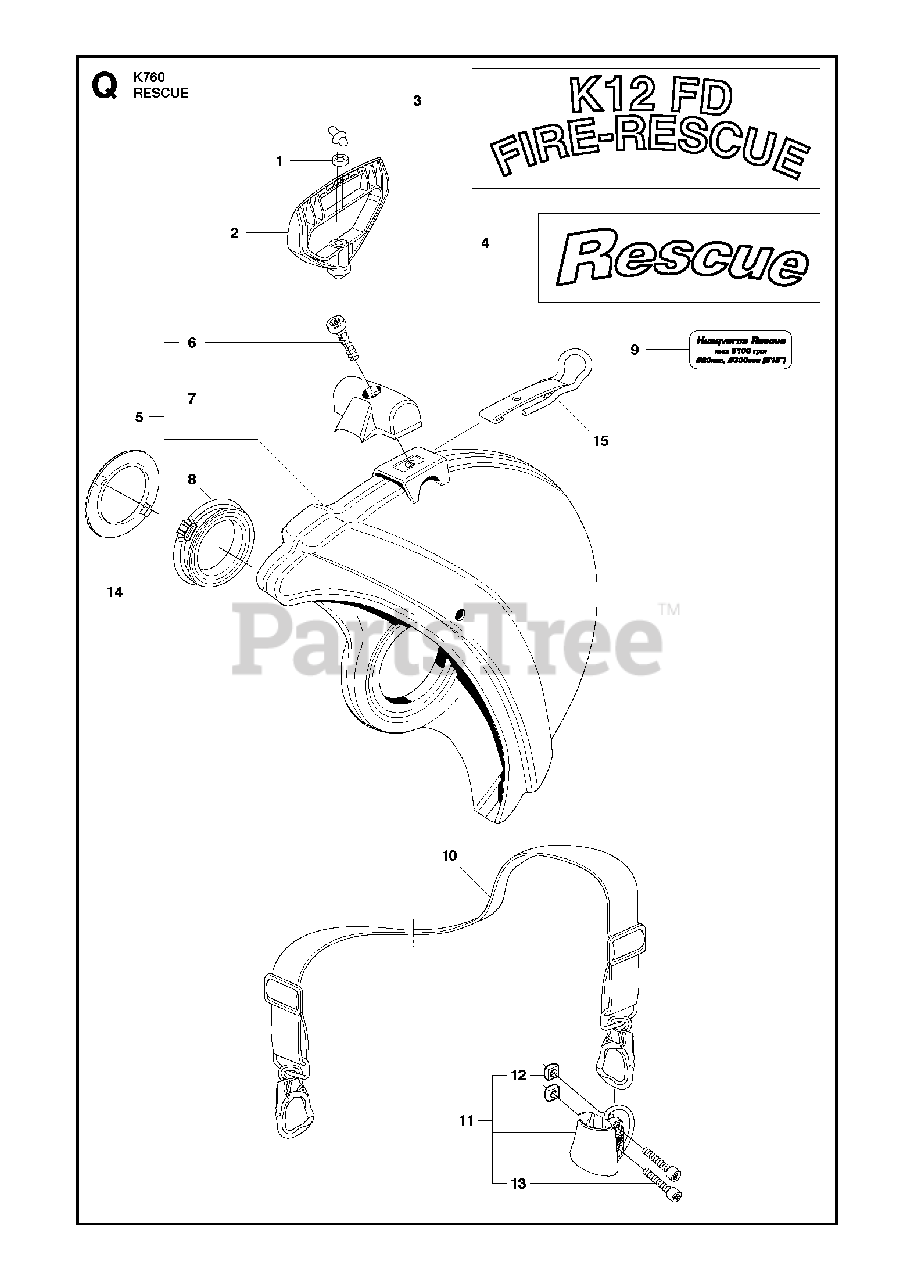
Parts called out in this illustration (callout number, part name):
2	STARTER HANDLE
5	BLADE GUARD"Rescue 12"". Incl. 6 - 8"
6	SCREW ITXSCM
13	SCREW ITXSCM
